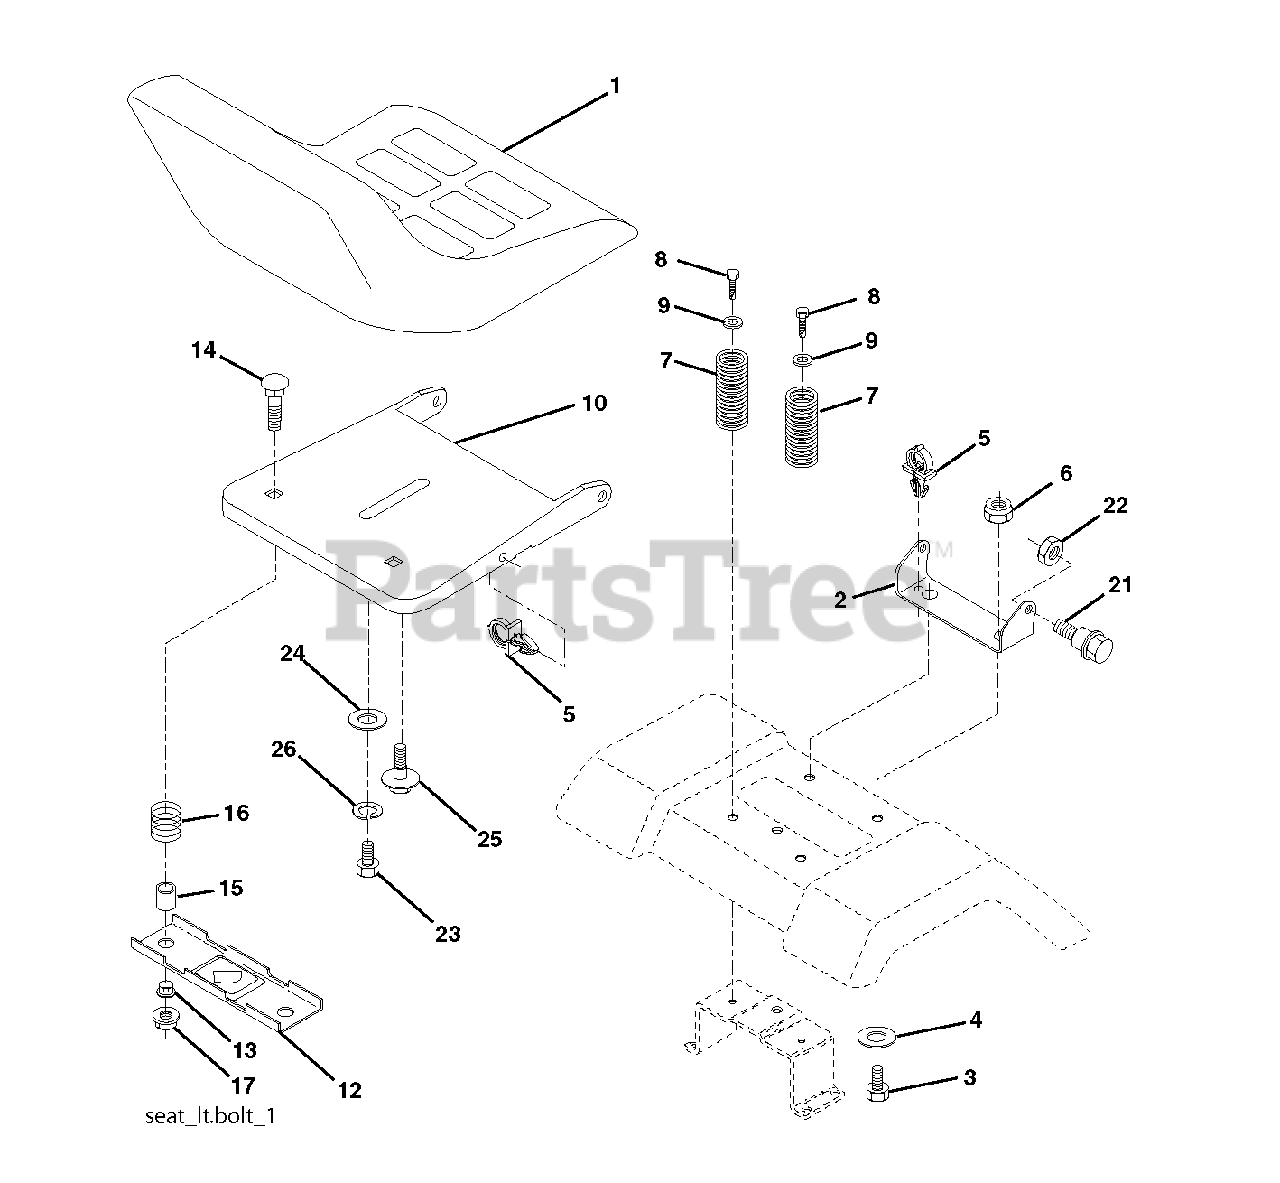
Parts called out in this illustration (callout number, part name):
1	SEAT.XG090.BLK.KB/BLT.NO-LOG
2	SEAT PIVOT BRKT
4	WASHER PM
5	PUSH CLIP
6	NUT
7	SPRING COMPRESSION
8	SCREW 3/8-16X1
9	WASHER
10	PAN.ASM.SEAT.1SLOT
12	BRKT.MNTNG.SWITCH.SEAT
14	BOLT.ROUND.HEAD.SQUARE.NECK
15	SPACER SPLIT 28X.96
17	NUT T
21	BOLT.SHOULDER.5/16-18
22	NUT.71038.31-18.HEX.NYLOCK
23	BOLT.HEX.BLACK
25	BOLT,SHOULD
26	LOCKWASHER
